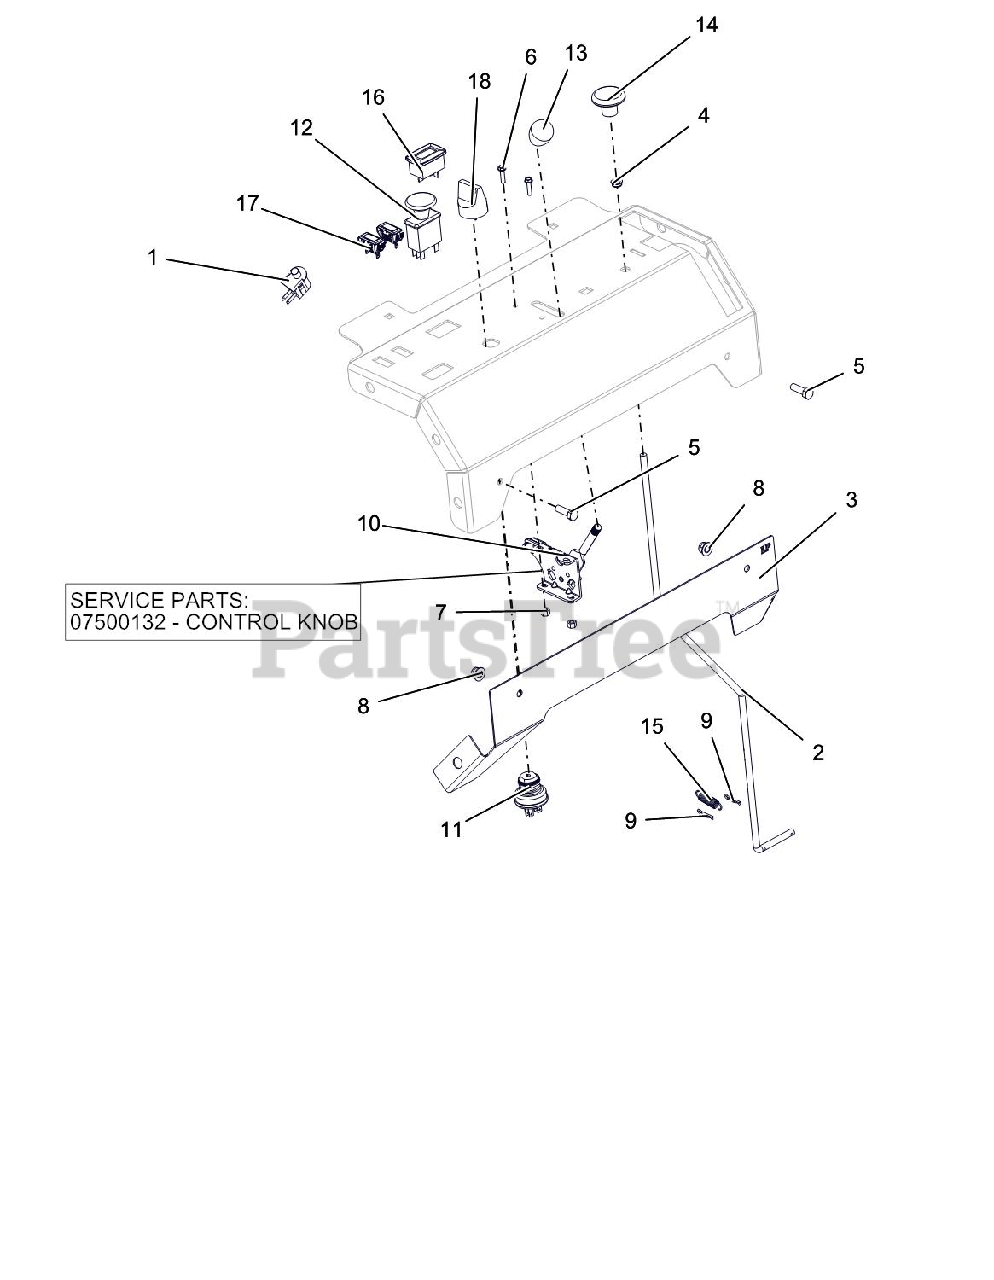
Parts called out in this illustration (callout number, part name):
1	SWITCH- SNAP MTG N.O.
2	WIREFORM, TRAILER LOCK
3	PLATE, FRONT BACKER
4	BUSHING, POLYLINER-.38 SNAPIN
5	@BLT-HEX .31-18X1.00 GR5 YWZC
6	@SCR-MCH 10-24X.75 HWH YWZC
7	@NUT-LK-NYL 10-24 W/INSRT YWZC
8	@NUT-LK-NYL-FLG .31-18 YWZC
9	PIN-HAIR, ENDRIES #25 YWZC
10	KNOB-CONTROL-BLACK .38-16X.50
10	CABLE, PRO-CONTROL
11	SWITCH, IGNITION
12	SWITCH, CLUTCH
13	KNOB-CONTROL-BLACK .38-16X.50
14	KNOB, PUSH-PULL .312-18
15	SG-TENS .048X.44X1.75 WLD 9
16	METER, HOUR W/MAINTENANCE
17	LIGHT,INDICATOR
18	KEY, W/ SHIELD
